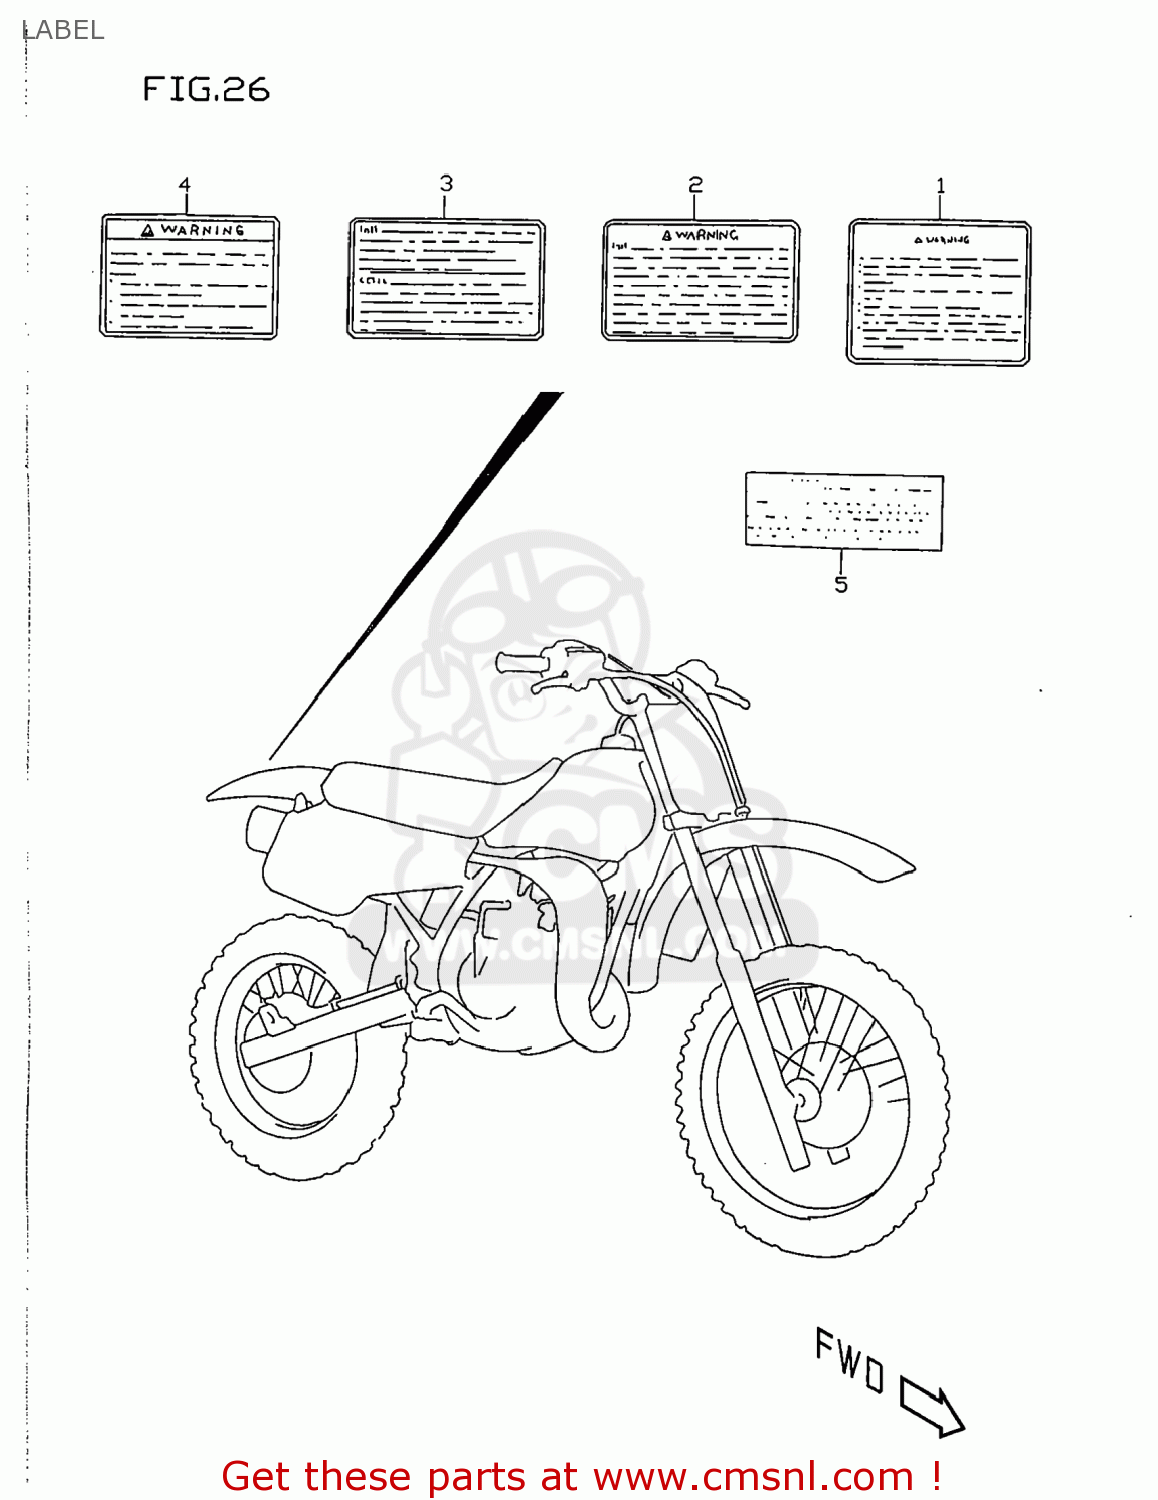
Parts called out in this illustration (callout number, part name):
1	LABEL,WARNING
2	LABEL,WARNING
3	LABEL,WARNING
4	LABEL,WARNING SAFETY
5	LABEL (MANUAL NOTICE)
6	MANUAL, OWNER'S
